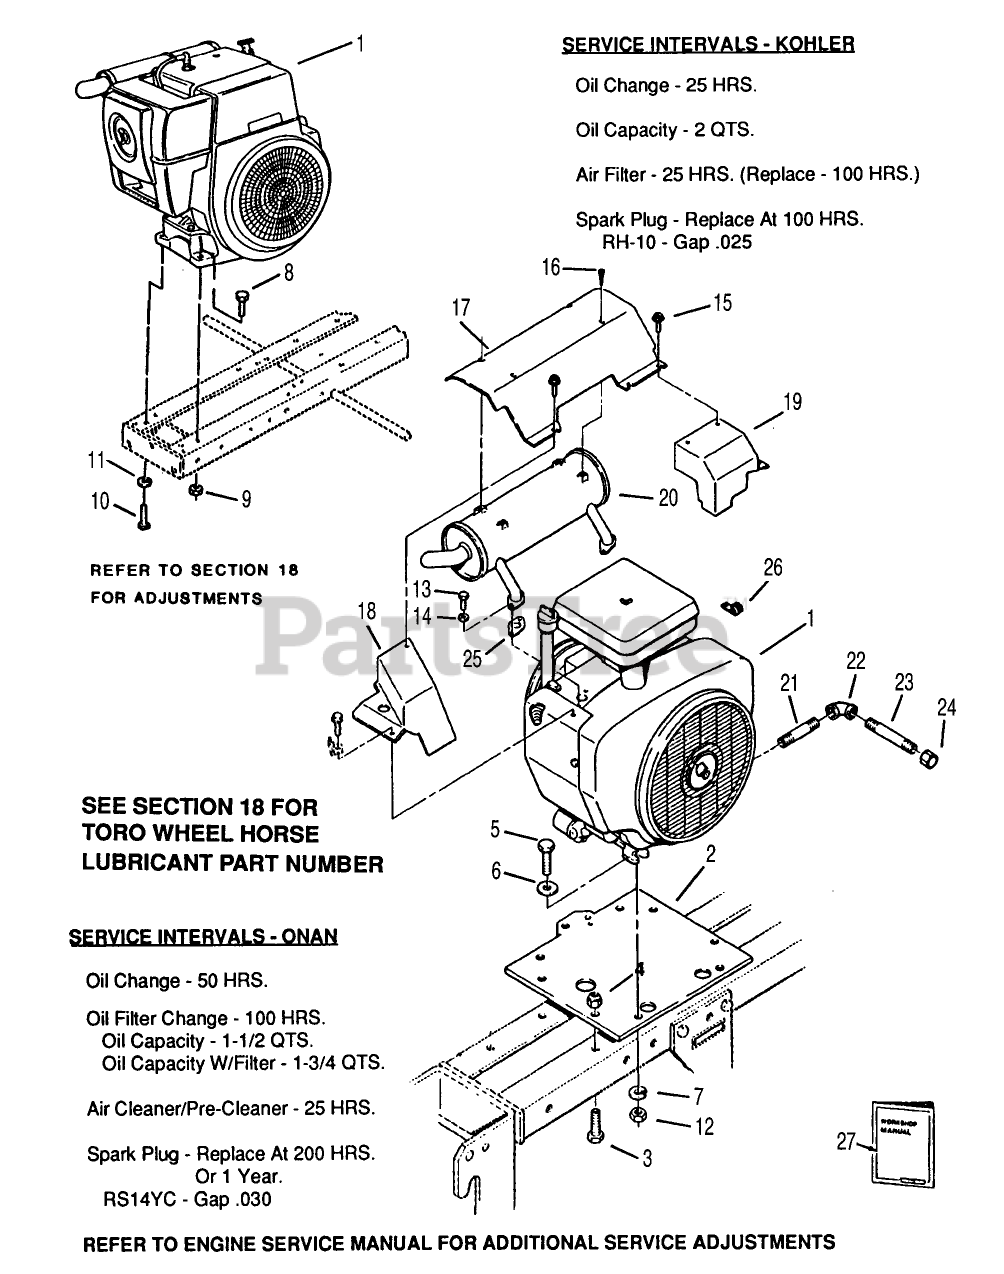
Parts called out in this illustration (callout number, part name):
2	PLATE-ENGINE *B
4	E.S. Nut 3/8-16
22	ELBOW 3/8 90 DEG
23	PIPE-NIPPLE 3/8 X 4"
26	J-CLIP
27	Magnum Kohler Service Repair Manual
